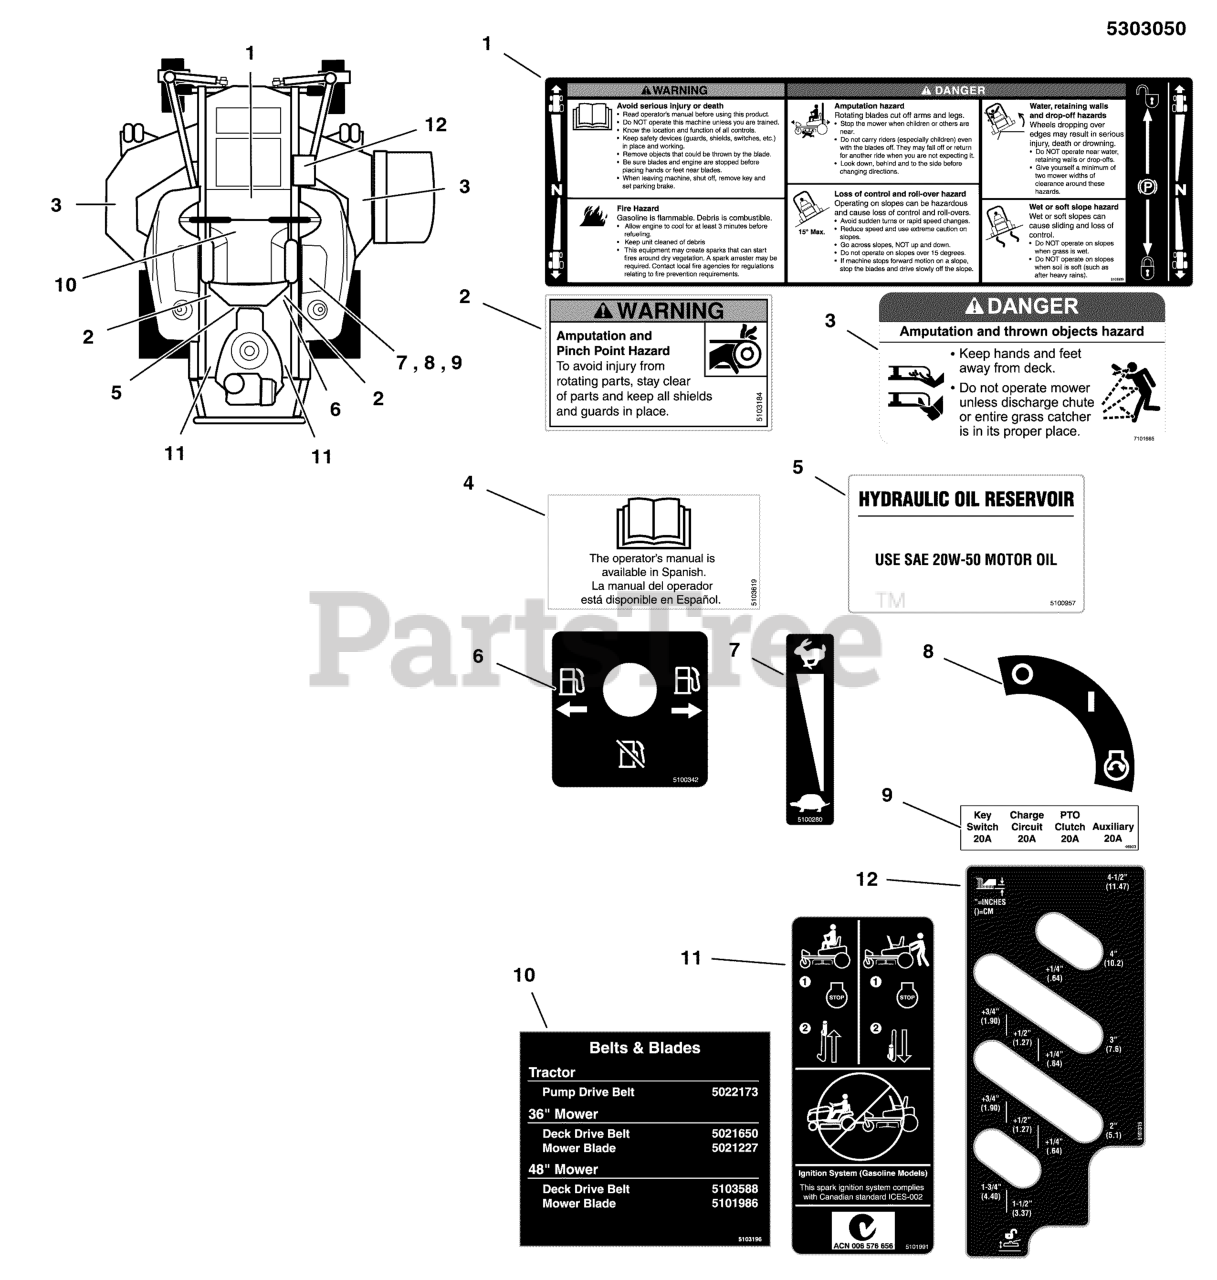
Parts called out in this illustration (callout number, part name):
1	DECAL, MAIN SAFETY
2	DECAL, WARNING, HAND IN BELT, ENG ONLY
3	DECAL, DANGER DO NOT OPERATE W/O DEFLECT
4	DECAL, MANUAL AVAILABLE IN SPANISH
5	DECAL, HYDRAULIC OIL, SAE 20W50
6	DECAL, FUEL VALVE
7	DECAL, THROTTLE CONTROL
8	DECAL, IGNITION SWITCH
9	DECAL, FUSE LOCATION
10	DECAL, BELT & BLADE, S50XT ICD
11	DECAL, TRANSAXLE RELEASE
12	DECAL, CUT HEIGHT, S50XT
